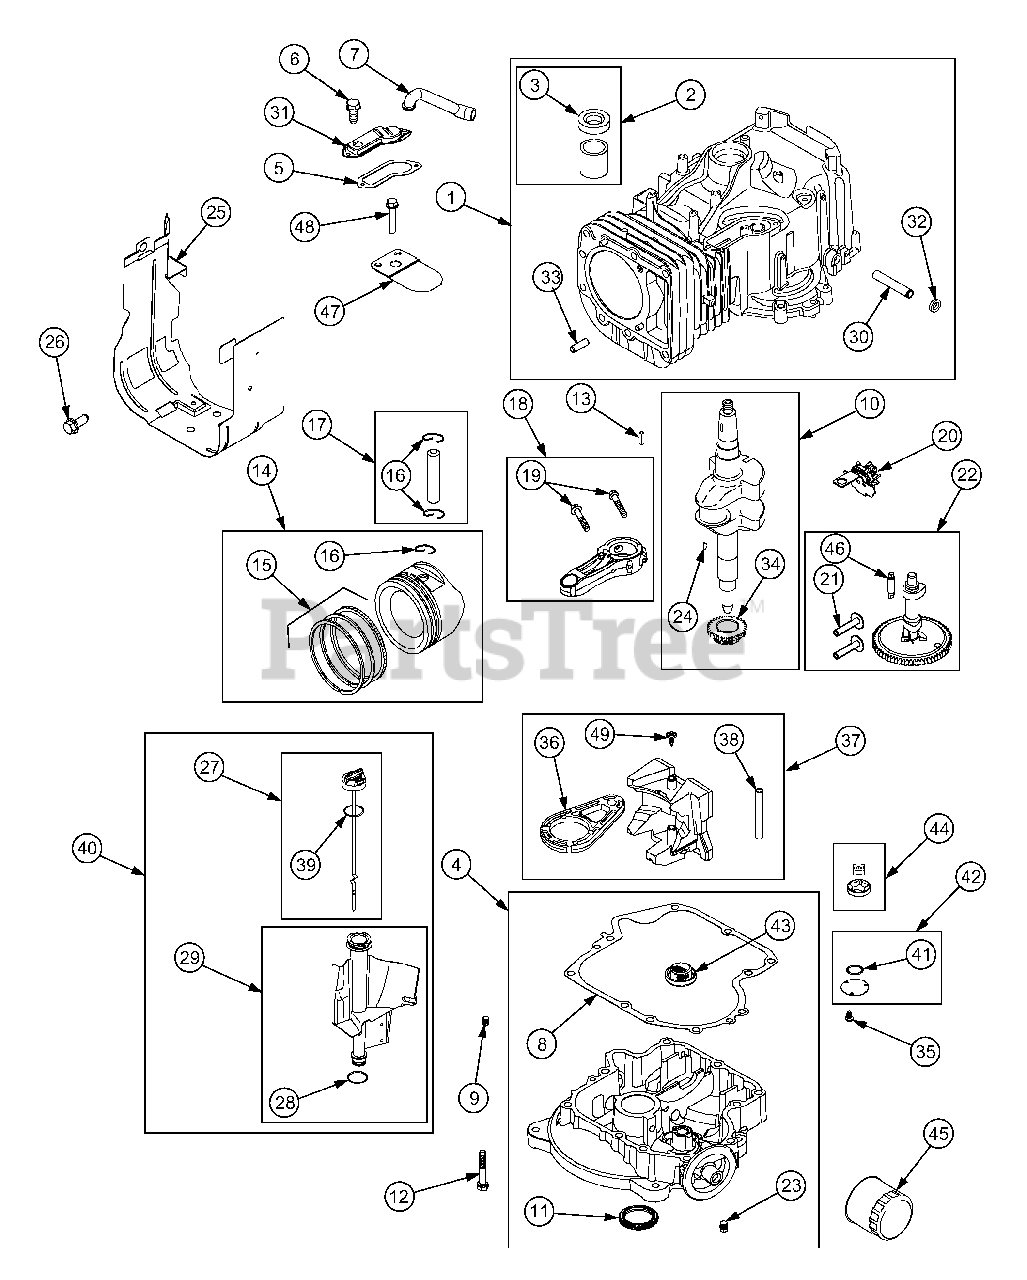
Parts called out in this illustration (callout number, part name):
1	Cylinder Assembly
2	Kit, Bushing/Seal (Magneto Side)
3	Seal, Oil
4	Sump, Engine
5	Gasket, Breather
6	Screw (Breather Assembly)
7	Tube, Breather
8	Gasket, Crankcase
9	Plug, Oil Drain
10	Crankshaft
11	Seal, Oil
13	Key, Flywheel
14	Piston Assembly (Standard)
15	Ring Set, Piston (Standard)
16	Lock Ring, Piston Pin
17	Pin, Piston (Standard)
18	Rod, Connecting (Standard)
19	Screw (Connecting Rod)
20	Slinger, Governor/Oil
21	Tappet, Valve
22	Camshaft
23	Plug, Oil
24	Key, Timing
25	Shield, Cylinder
27	Dipstick
28	Seal, Dipstick Tube
29	Tube, Dipstick
30	Bushing, Governor Lever
31	Cover, Breather Passage
32	Seal, Governor Shaft
33	Pin, Locating
34	Gear, Timing
35	Screw (Oil Pump Cover)
36	Link, Counterweight
37	Counterweight
38	Pin, Counterweight
39	Seal, O-Ring (Dipstick Tube)
40	Dipstick/Tube Assembly
41	O-Ring Seal (Oil Pump Cover)
42	Cover, Oil Pump
43	Screen, Oil Pump
44	Pump, Oil
45	Filter, Oil
46	Shaft, Pump
47	Reed, Breather
49	Plug, AVS Counterweight
